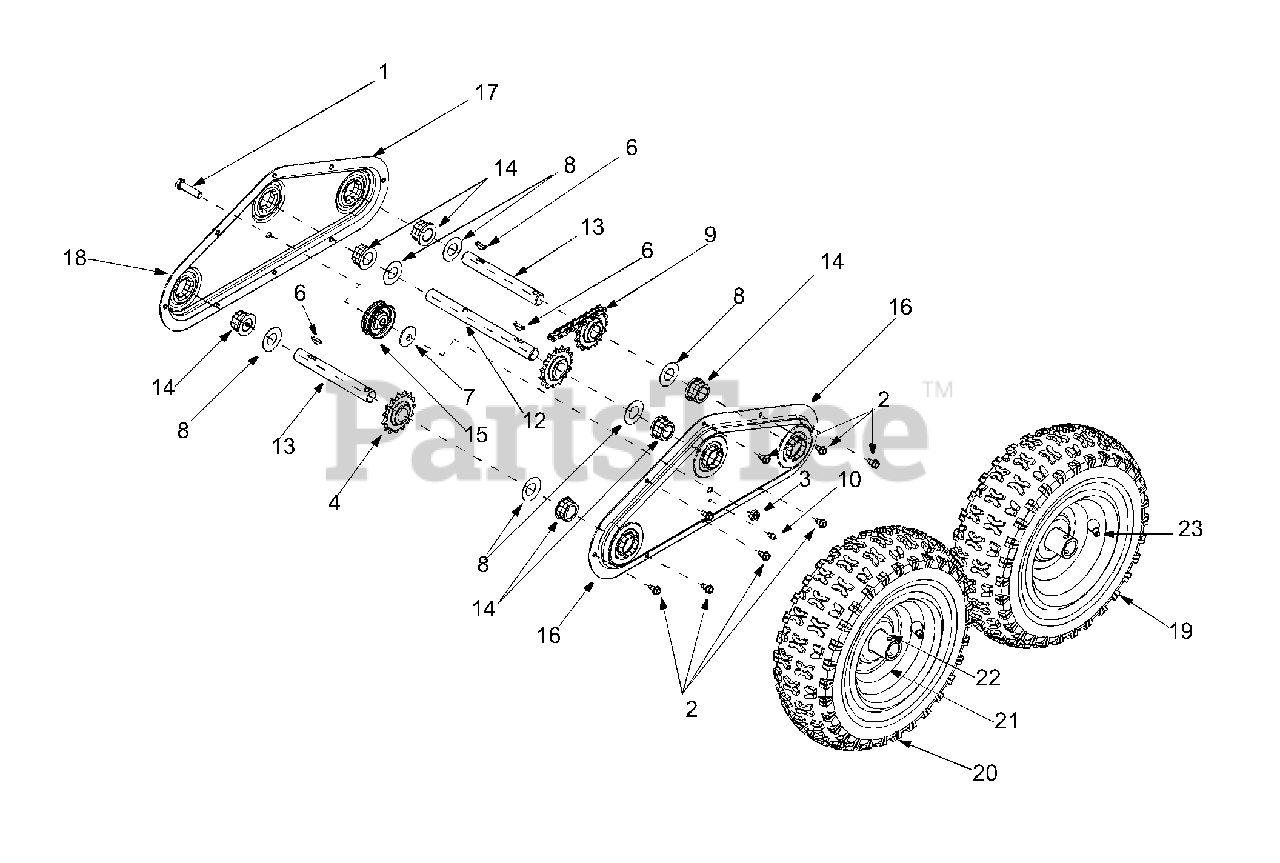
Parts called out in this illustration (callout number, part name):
1	Special Hex Screw: 3/8-24 x 1.5"
2	TT Screw: 1/4-20 x 0.5"
3	Jam Nut
4	Sprocket
7	Flat Washer
8	Flat Washer
9	Lubricant: 6in 1
10	Lube Fitting
12	Drive Axle
13	Wheel Axle
14	Hex Flange Bearing
15	Flat Idler
18	Chain Case Assembly RH
18	Chain Case Assembly LH
23	Air Valve
